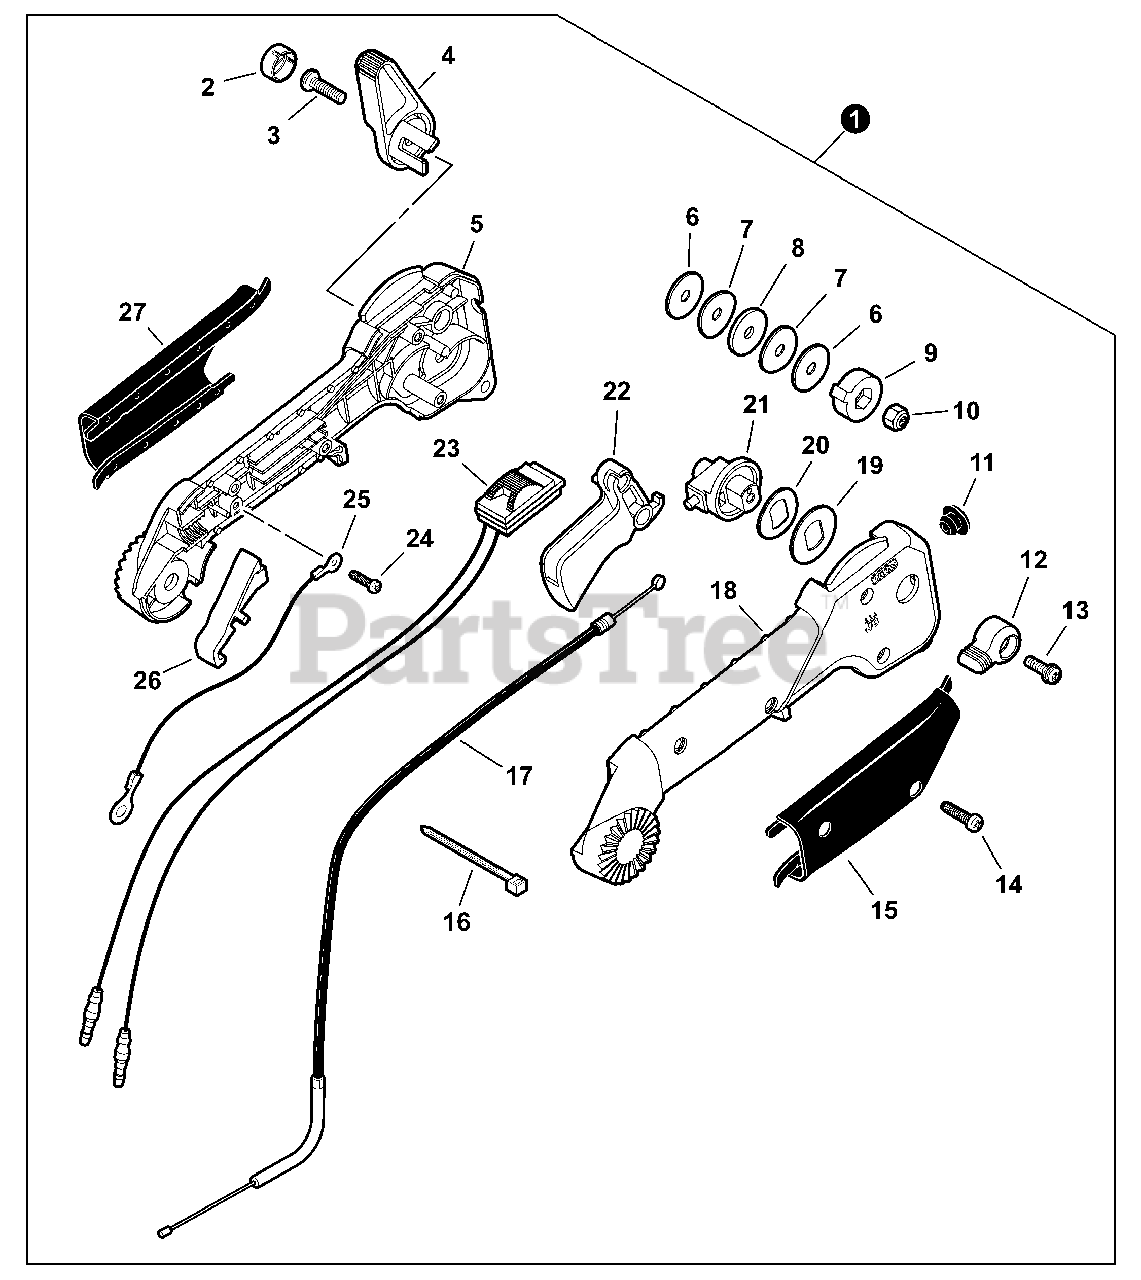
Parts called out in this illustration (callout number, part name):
1	THROTTLE CONTROL ASSY
2	CAP, BOLT
3	BOLT, ADJUSTING M6
4	CONTROL, THROTTLE
5	CONTROL HANDLE - LEFT
6	WASHER M6
7	WASHER, SPRING
8	WASHER M6
9	LEVER, THROTTLE
10	NUT, NYLON M6
11	PLUG, THROTTLE LIMITER
12	LEVER, THROTTLE LIMITER
13	SCREW M4
14	SCREW, HANDLE M4
15	GRIP, RIGHT
17	CABLE, THROTTLE
18	CONTROL HANDLE - RIGHT
20	WASHER, WAVE
21	LIMITER ASSY, THROTTLE
22	TRIGGER, THROTTLE
23	SWITCH, ON-OFF
24	SCREW M3
25	LEAD - GROUND
26	COVER, HANDLE REAR
27	GRIP, LEFT
